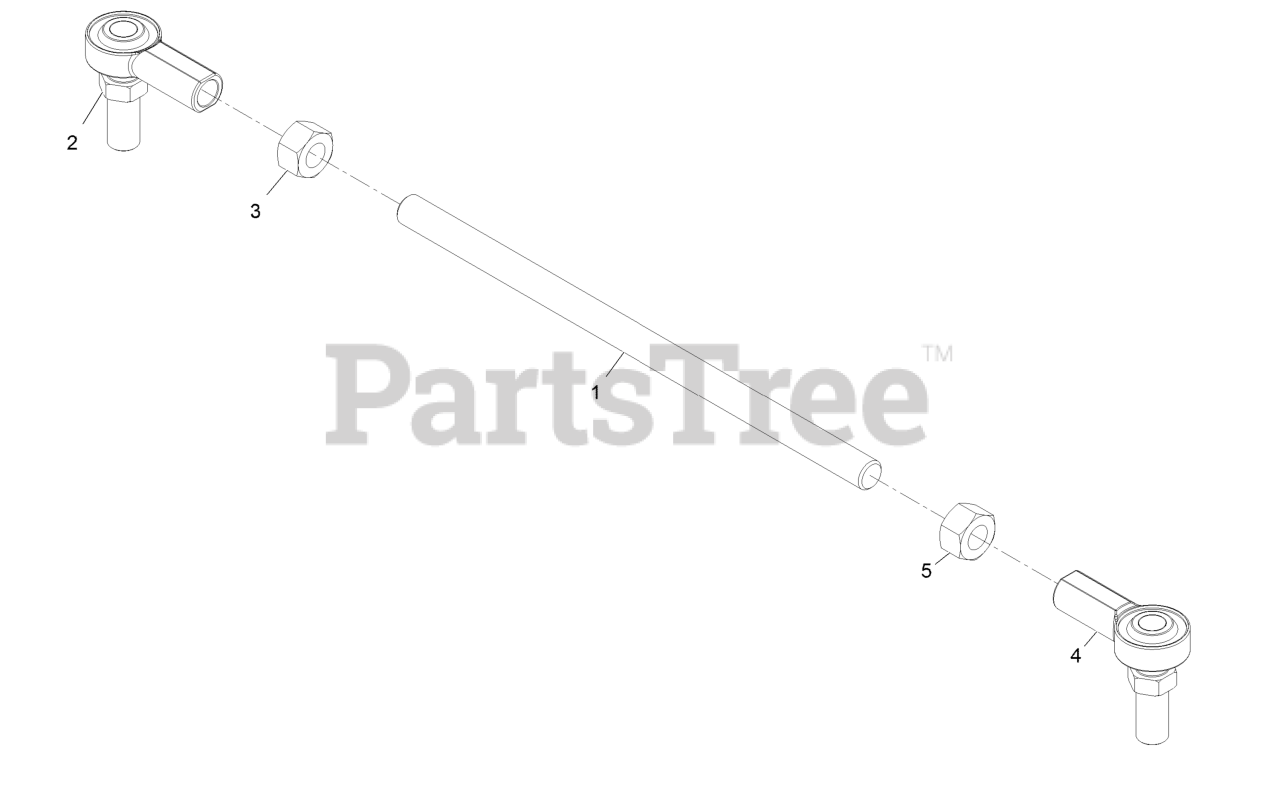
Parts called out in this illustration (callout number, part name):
1	Rod-Linkage, Steering
2	Rod-End, RH
3	Nut-Hex
4	Rod-End, LH
5	Nut-Hex, LH
